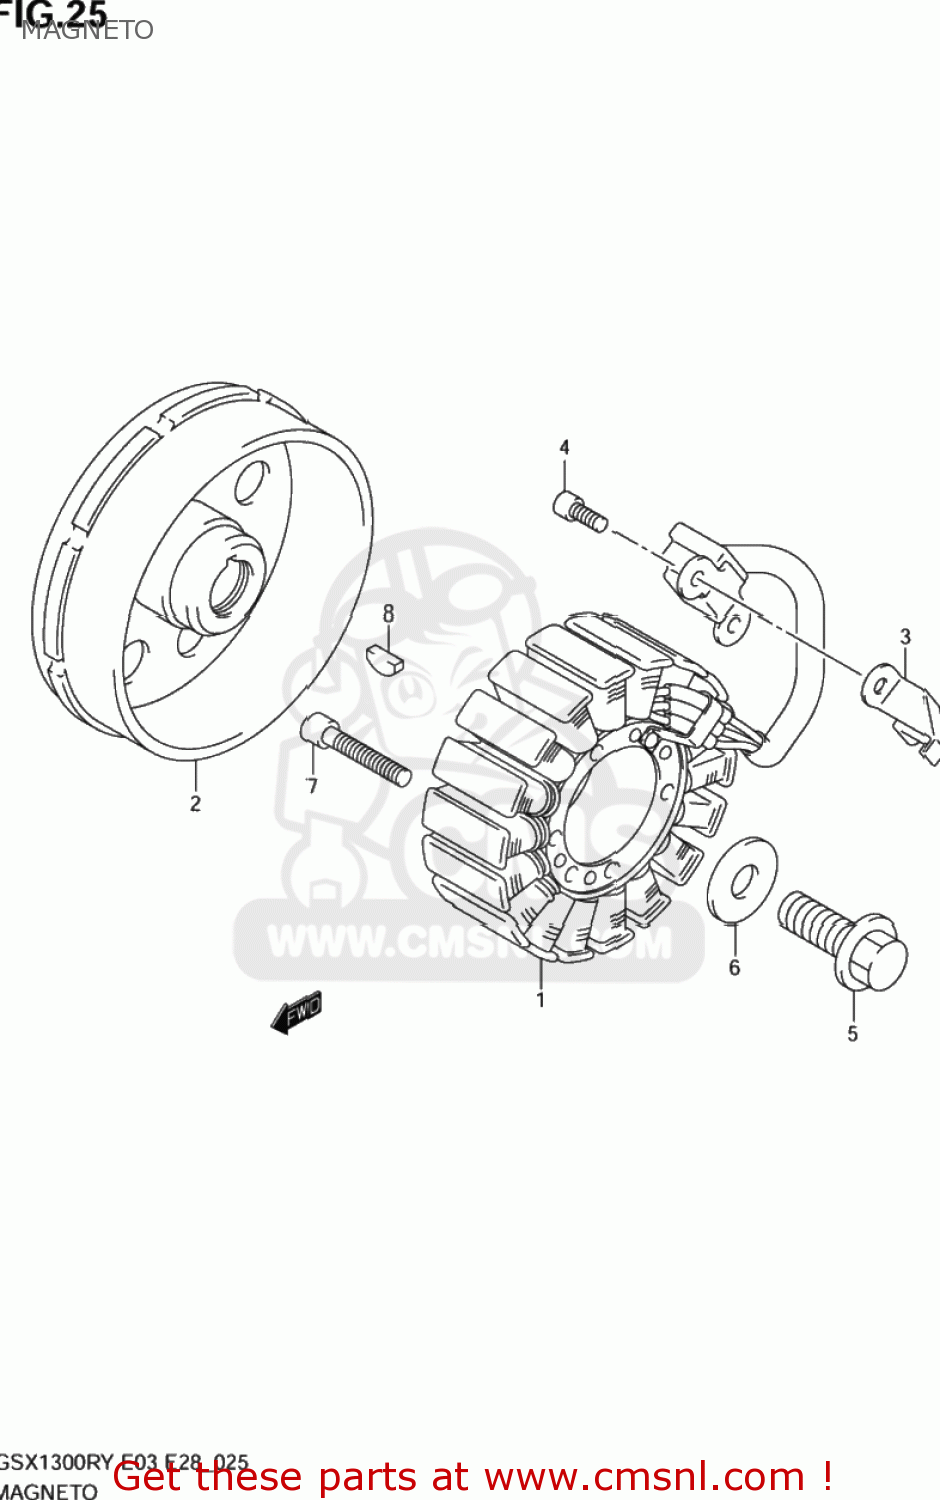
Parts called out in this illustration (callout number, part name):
1	STARTER ASSY
2	ROTOR ASSY
3	CLAMP,MAGNETO LEAD
4	BOLT
5	BOLT(12X30)
6	WASHER(12X30X3)
7	BOLT
8	KEY
